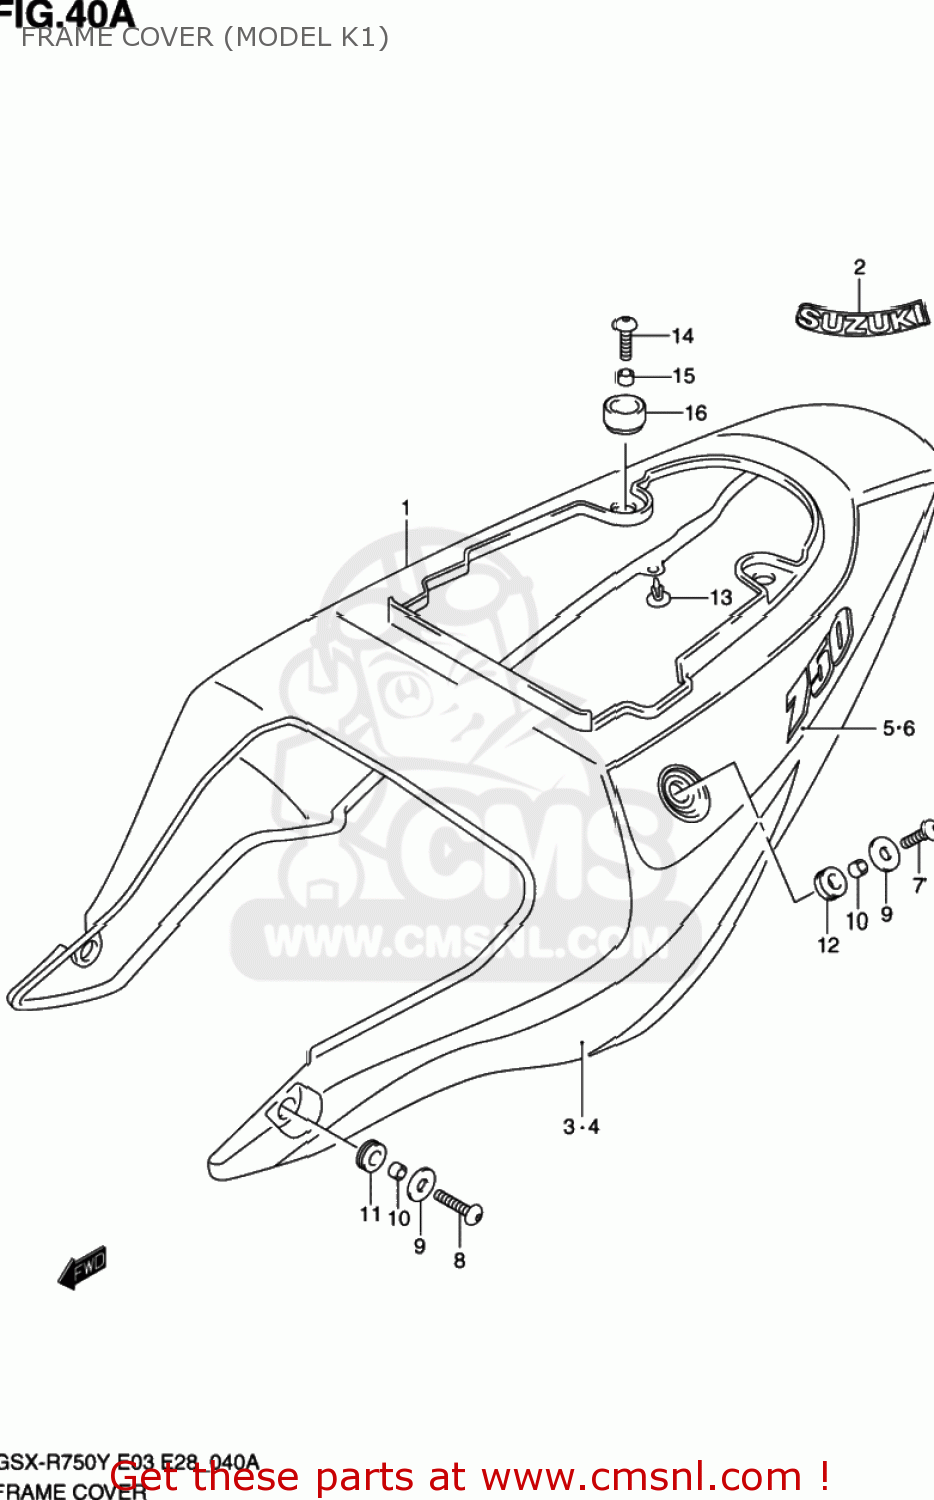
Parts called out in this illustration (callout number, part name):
1	COVER ASSY,FRAME
2	EMBLEM,SUZUKI
3	TAPE,FRAME COVER,R
4	TAPE,FRAME COVER,L
5	TAPE,FRAME COVER,R
6	TAPE,COVER,L
7	SCREW(6X25)
8	SCREW(6X30)
9	WASHER(6.5X20X2)
10	SPACER(6.5X10X7)
11	CUSHION,FRAME COVER FR
12	CUSHION,FRAME COVER SIDE
13	CLIP(BLACK)
14	SCREW(6X25)
15	SPACER(6.5X10X9.4)
16	CUSHION
